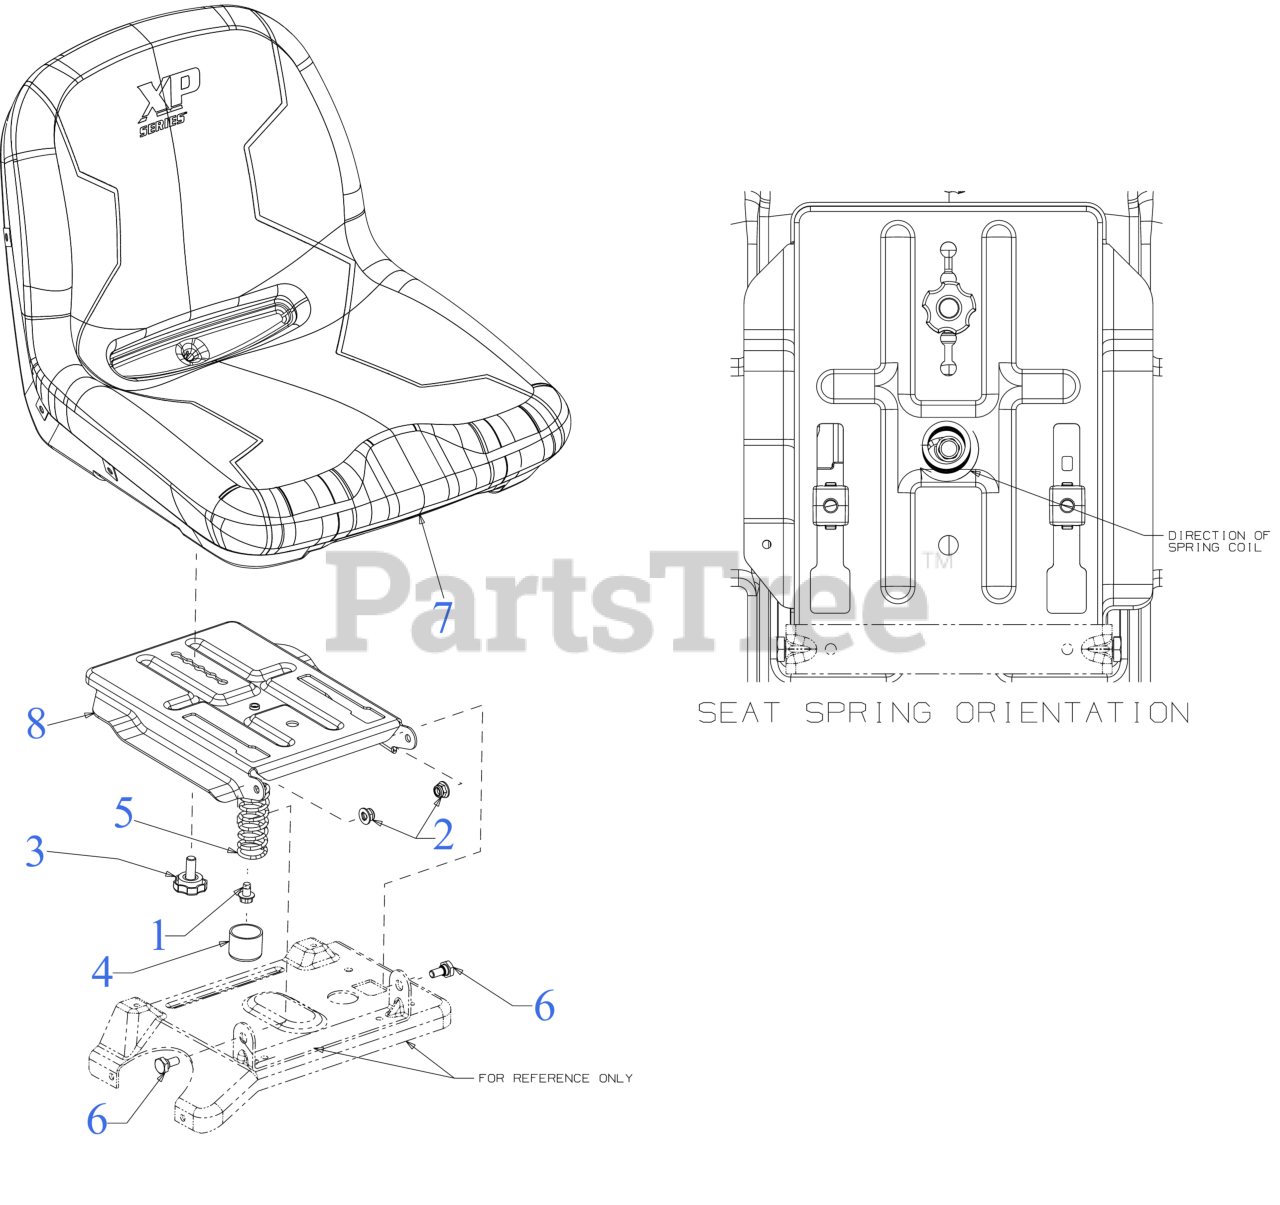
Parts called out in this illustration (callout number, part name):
1	SCREW 5/16-18 x .500
2	FLANGE LOCK NUT 5/16-18
3	SEAT ADJUSTMENT KNOB
4	SEAT SPRING CAP
5	SEAT SPRING
6	SHOULDER SCREW .437
7	SEAT (HI/TROY XP/FLAT/EL)
8	MANUAL SEAT ADJUSTMENT BRACKET
